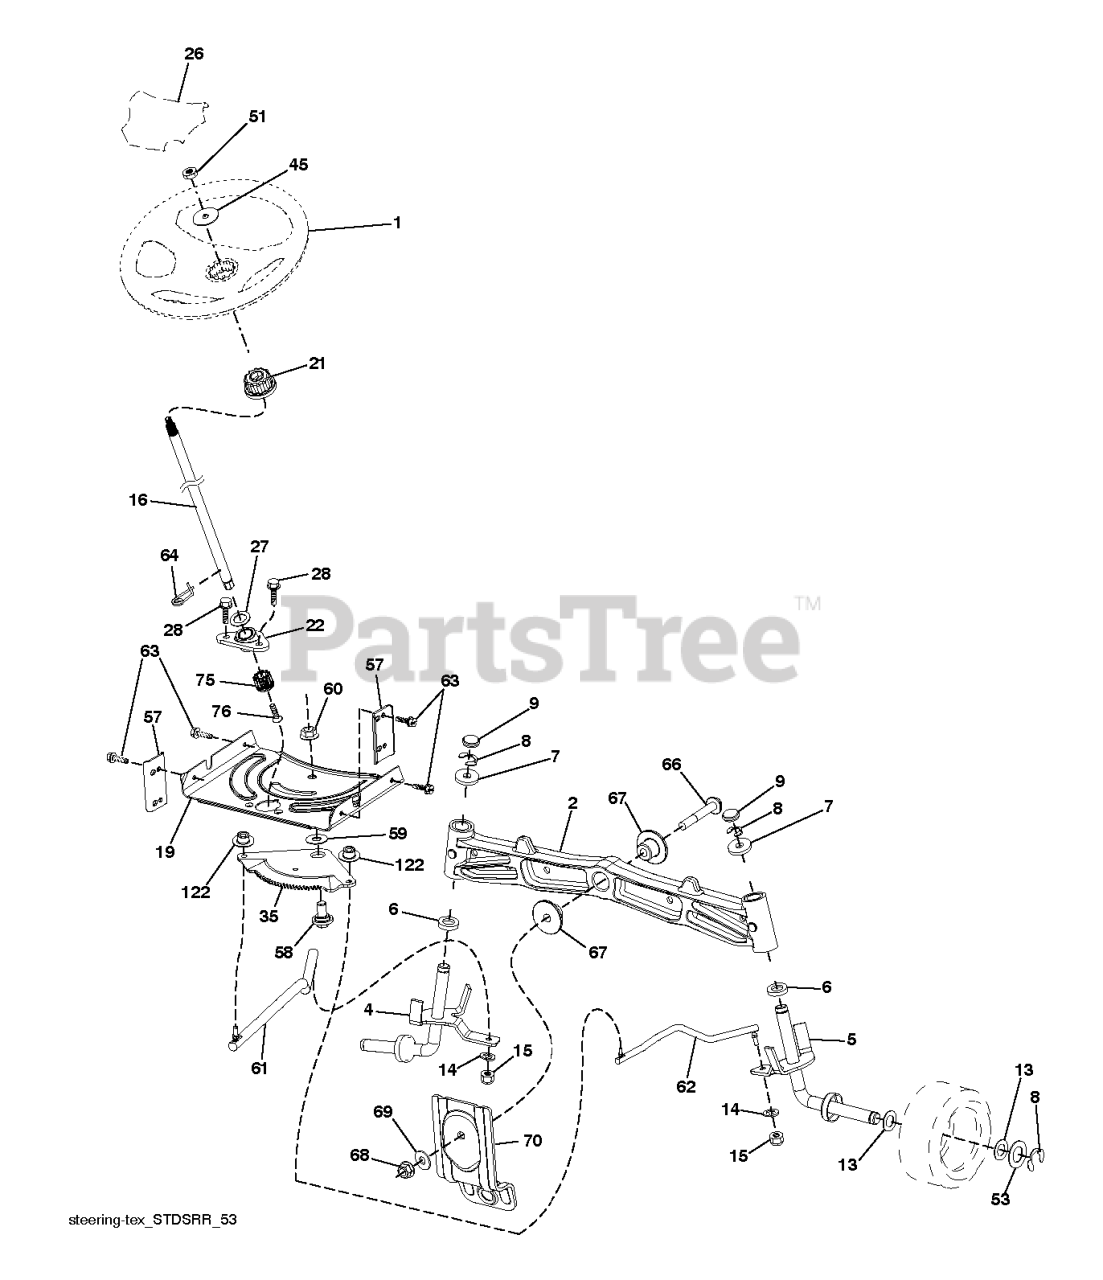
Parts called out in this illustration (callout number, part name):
1	WHEEL.STEER.HUSQ.SR.498.OVMLD
2	AXLE.CAST.IRON
4	SPINDLE.WELDED.LH.15"TEX
5	SPINDLE.WELDED.RH.15"T
6	THRUST WASHER
9	CAP.SPINDLE.BLACK
14	SLW 3/8 STD
15	NUT CROWNLOCK 3/8-24
16	SHAFT.STEER.2HIGH.SPLND.PLATED
19	PLATE.STEER.DDL.NLT/NG
21	ADAPTER.WHEEL.STEER.SPLND.ALUM
22	BEARING.SHAFT.STEER.LOWER.625
26	INSERT.CAP.WHL.STRG.HUSQ.PREM
28	SCREW, 3/8-16X3/4
35	GEAR.SECTOR.PLATE.DDL.
45	WASHER.3/8ID.2-3/8OD.12GA.PLTD
51	NUT LOCK FLG 3/8-16 UNC
53	WASHER.HARDENED
57	BRACKET.UPSTOP.TEX
58	BOLT.SHOULDER.SECTOR.P
59	WASHER.THURST.SECTOR.S
60	NUT FLANGE LOCK 5/8-11
61	LINK.ASM.DRAG.ADJUST.LH.RAW
62	LINK.ASM.DRAG.ADJUST.RH.RAW
63	SCREW
64	RETAINER.CLIP.SPRING.S
66	BOLT HEX FGHD 7/16-14 X 3 SERR
67	BUSHING.PM.FRONT AXLE
68	NUT.LOCK.FLANGE.7/16
69	WASHER.1.5X.505X.118
70	BRACKET.FRT.DECK.SUSP.RR.MT431
75	PINION.ZINC PLATED
76	SCREW HEAD SOCKET LRVB
122	CAP.GEAR.SECTOR.TEX
